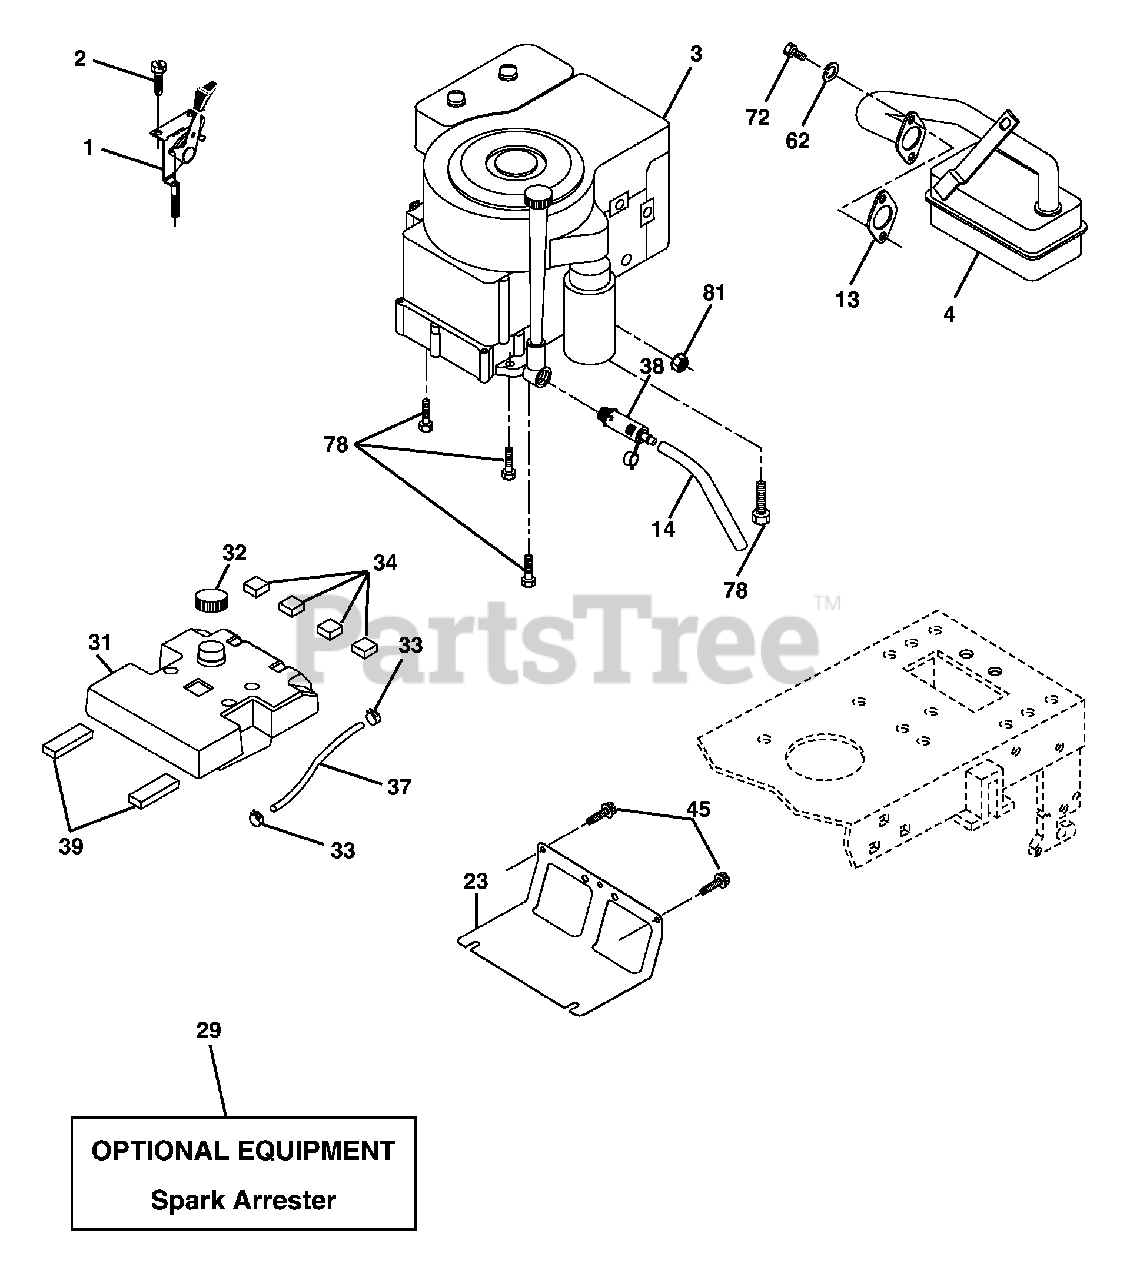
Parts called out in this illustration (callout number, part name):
1	Control, Throttle
2	Screw 10 x 3/4 Single Lead Hex
4	Muffler
13	Muffler Gasket
14	Tube Oil Drain
23	Shield, Browning/Debris Guard
29	Arrester, Spark
31	Tank, Fuel
32	Cap, Fuel
33	Clamp, Hose Blk
34	Pad Spacer
37	Line, Fuel
38	Plug Drain Oil Easy
39	Pad Idler
45	Screw Hex Wsh Thdrol 3/8-16 x 3/4
62	Washer Split
72	Screw Hex Hd Cap 5/16-18 x 3/4
78	Screw 3/8-16 x 1-1/4
81	Nut Keps Hex 1/4-20 unc
